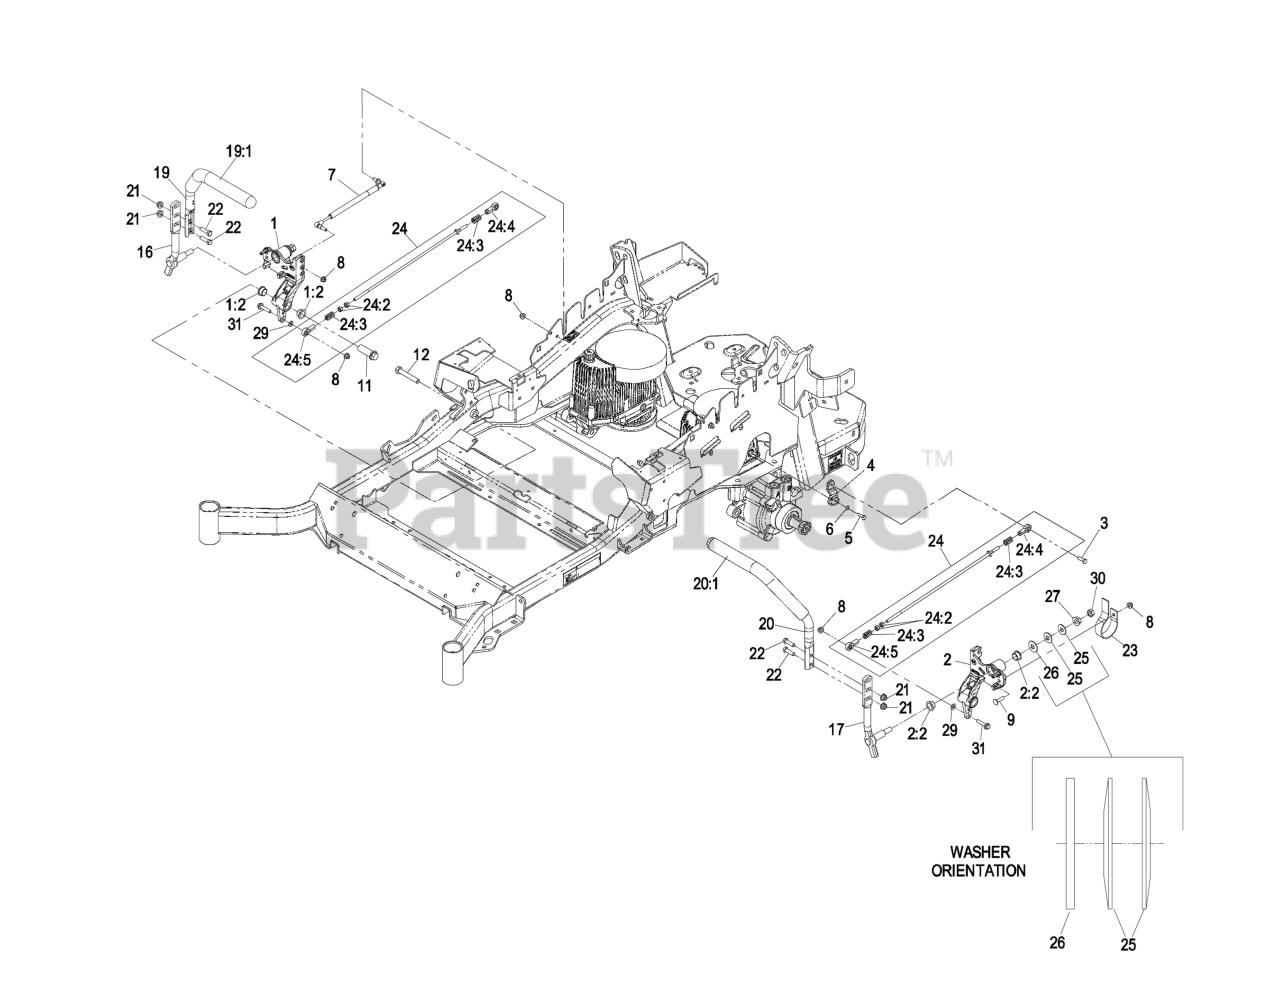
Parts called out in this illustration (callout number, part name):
1	RH MOTION CONTROL AND BUSHING ASM
1:2	BUSHING-FLANGE
2	LH MOTION CONTROL AND BUSHING ASM
2:2	BUSHING-FLANGE
3	SCREW-HH, THREAD LOCKING
4	ARM-CONTROL, PUMP
5	SCREW-HH
6	WASHER-SPRING
7	DAMPER-CONTROL, MOTION
8	NUT-HF, NI
9	BOLT-CARR
11	HUB-THREADED
12	SCREW-HH
16	LEVER-CONTROL MOTION, RH
17	LEVER-CONTROL MOTION, LH
19	RH STEERING HANDLE ASM
19:1	GRIP-LEVER, CONTROL
20	LH STEERING HANDLE ASM
20:1	GRIP-LEVER, CONTROL
21	NUT-HF, NI
22	SCREW-HH
23	SPRING-LEAF
24	FRONT PUMP LINKAGE ASM
24:2	NUT-HEX
24:3	SPRING-COMPRESSION
24:4	BALLJOINT-LH
24:5	BALLJOINT-RH
25	WASHER-SPRING
26	WASHER-FLAT
29	WASHER-PLAIN
30	NUT-JAM
31	SCREW-HHF
